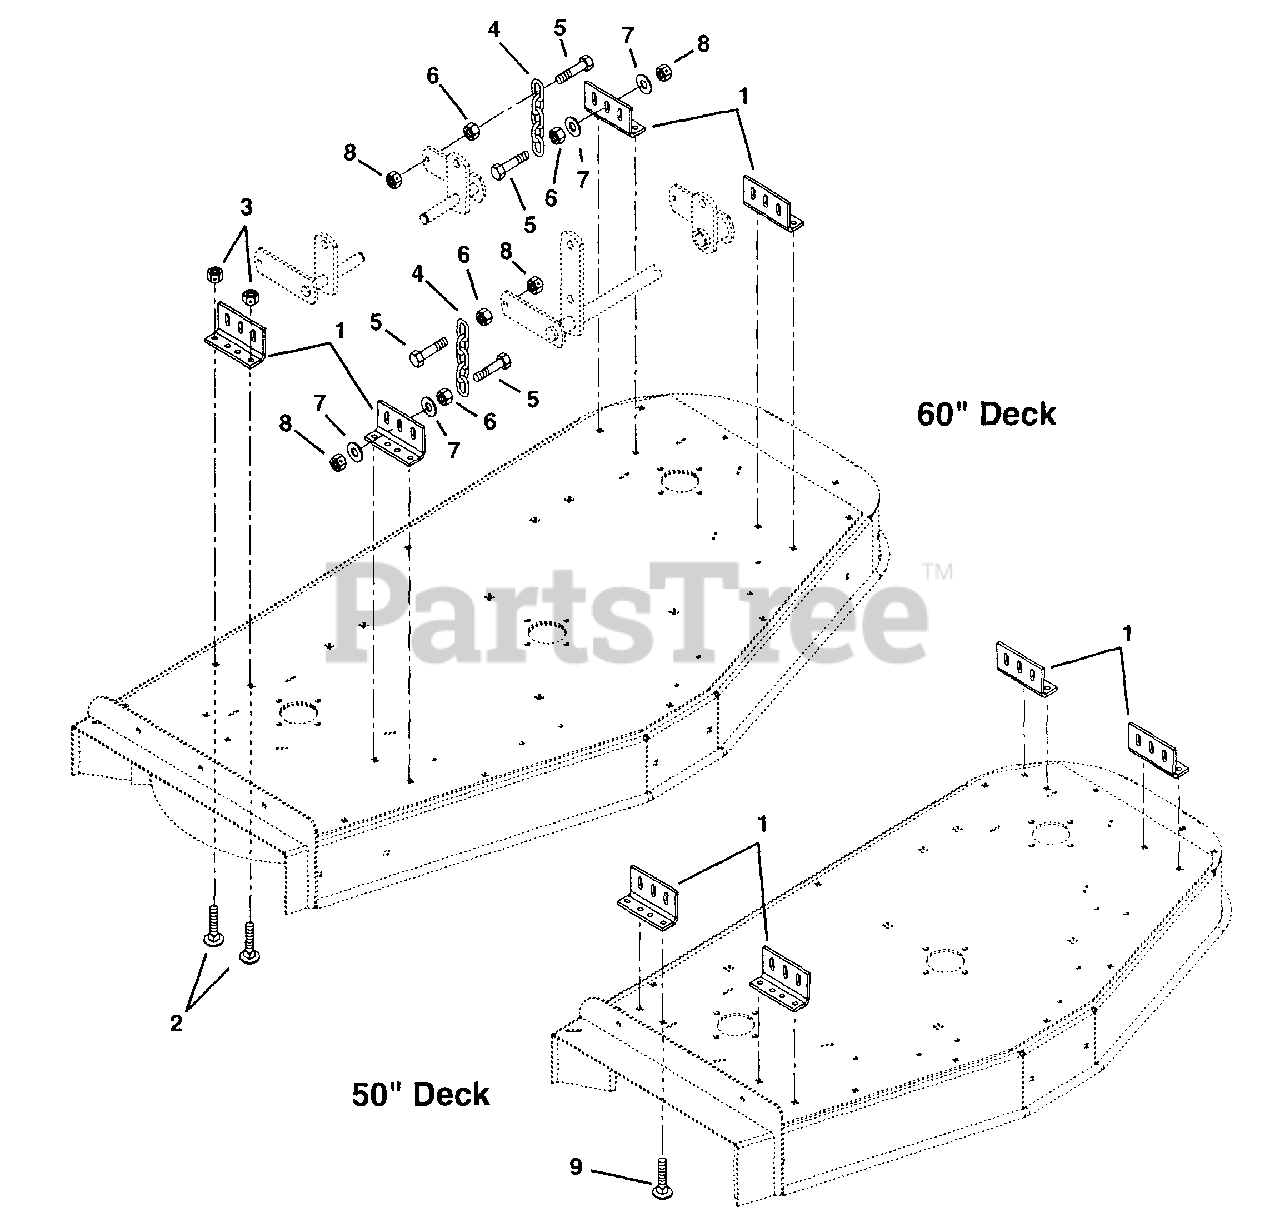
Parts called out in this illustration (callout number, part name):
1	Bracket, Mower Mounting
2	Bolt-Round Head Square Neck .38-16 x 1.25 Grade 2 (60" Deck)
2	Bolt-Round Head Square Neck .38-16 x 1.25 Grade 2 (50" Deck)
3	Nut-Locking-Nylon .38-16
4	Chain, Link
5	Bolt-Hex .38-16 x 1.50 Grade 5
6	Nut-Hex .38-16
7	Washer-Flat-Steel .406 x .812 x .065
8	Nut-Locking-Center .38-16
9	Bolt-Round Head Square Neck .38-16 x 1.50 Grade 2 (50" Deck)
